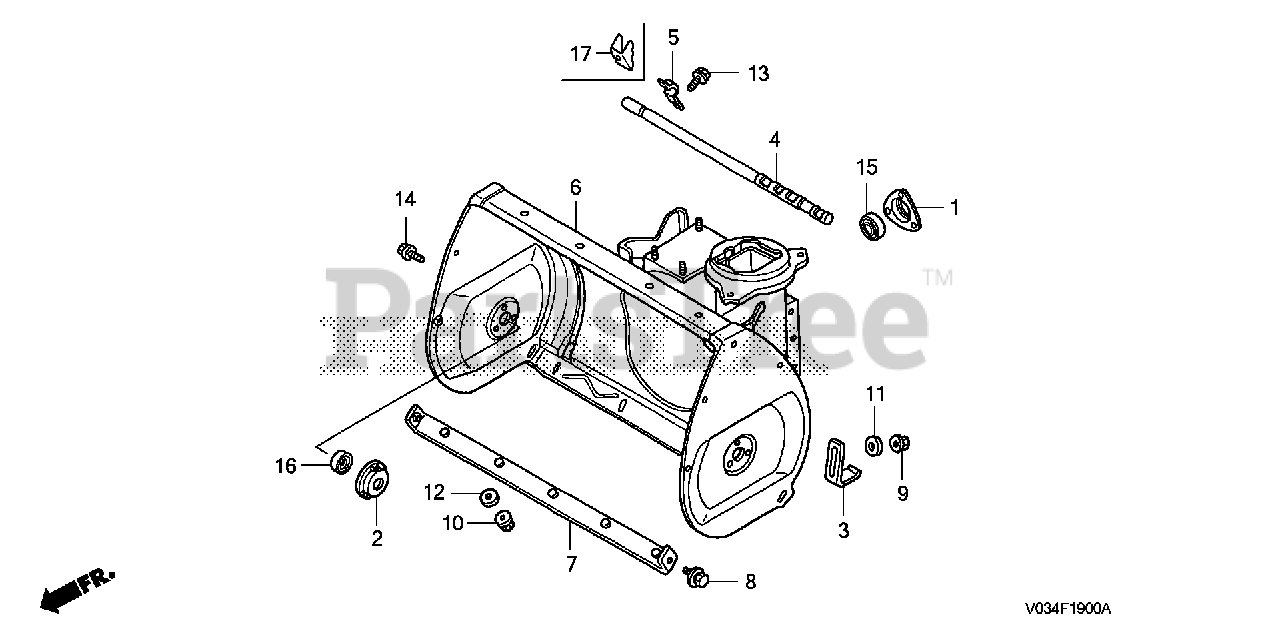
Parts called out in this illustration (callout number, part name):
1	HOLDER, WHEEL SHAFT BEARING
2	HOLDER, AUGER BEARING
3	SKID, AUGER
4	BAR, SNOW DROP
5	BRACKET, SNOW DROP BAR
6	HOUSING, AUGER
7	GUARD, AUGER HOUSING
8	BOLT-WASHER (8X16)
9	NUT, FLANGE (6MM)
10	NUT, FLANGE (8MM)
11	WASHER, PLAIN (6MM)
12	WASHER, PLAIN (8MM)
13	BOLT, FLANGE (6X8)
13	BOLT, FLANGE (6X12)
14	BOLT, FLANGE (6X10)
14	BOLT, FLANGE (6X12)
15	BEARING, RADIAL BALL (6004UU)
16	BEARING, RADIAL BALL (6203UU)
17	PLATE, SNOW DROP BAR
